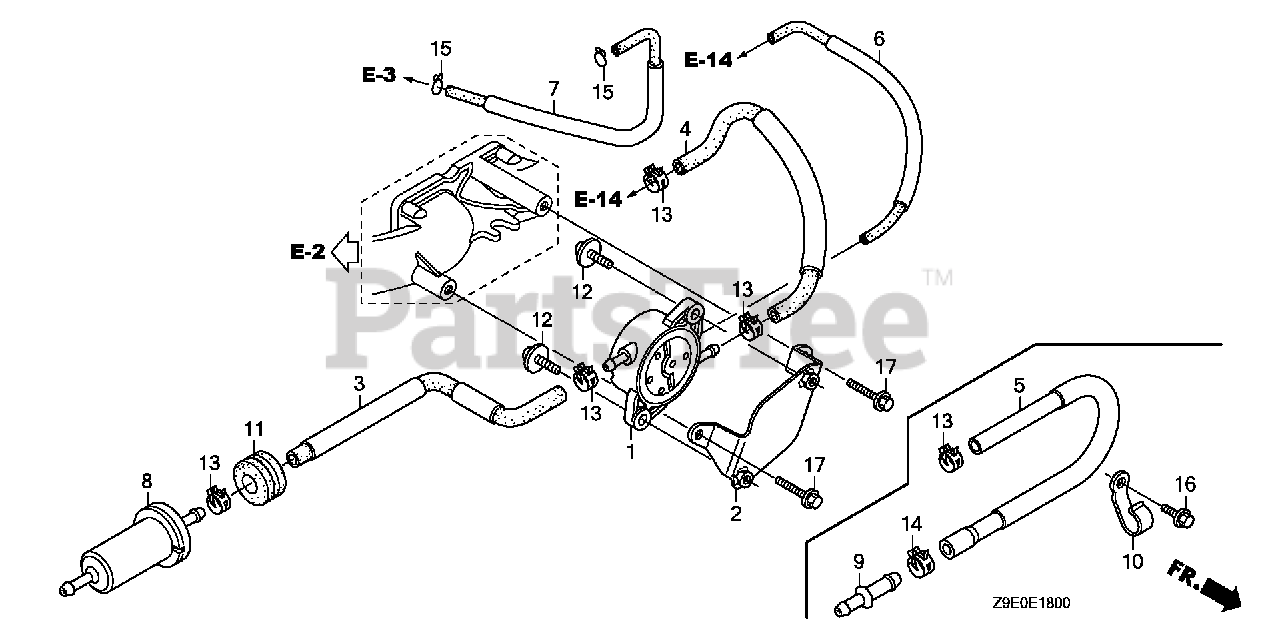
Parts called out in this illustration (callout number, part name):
1	PUMP ASSY., FUEL (MSDS)
2	STAY, FUEL PUMP
3	TUBE A, FUEL (FKM)
4	TUBE B, FUEL (FKM)
6	TUBE, PURGE
7	TUBE, DIAPHRAGM
8	FILTER, FUEL
11	RUBBER, RR. FENDER
12	SCREW-WASHER (6X16)
13	CLAMP, TUBE (D10)
15	CLIP, TUBE (C11)
17	BOLT, FLANGE (6X14)
